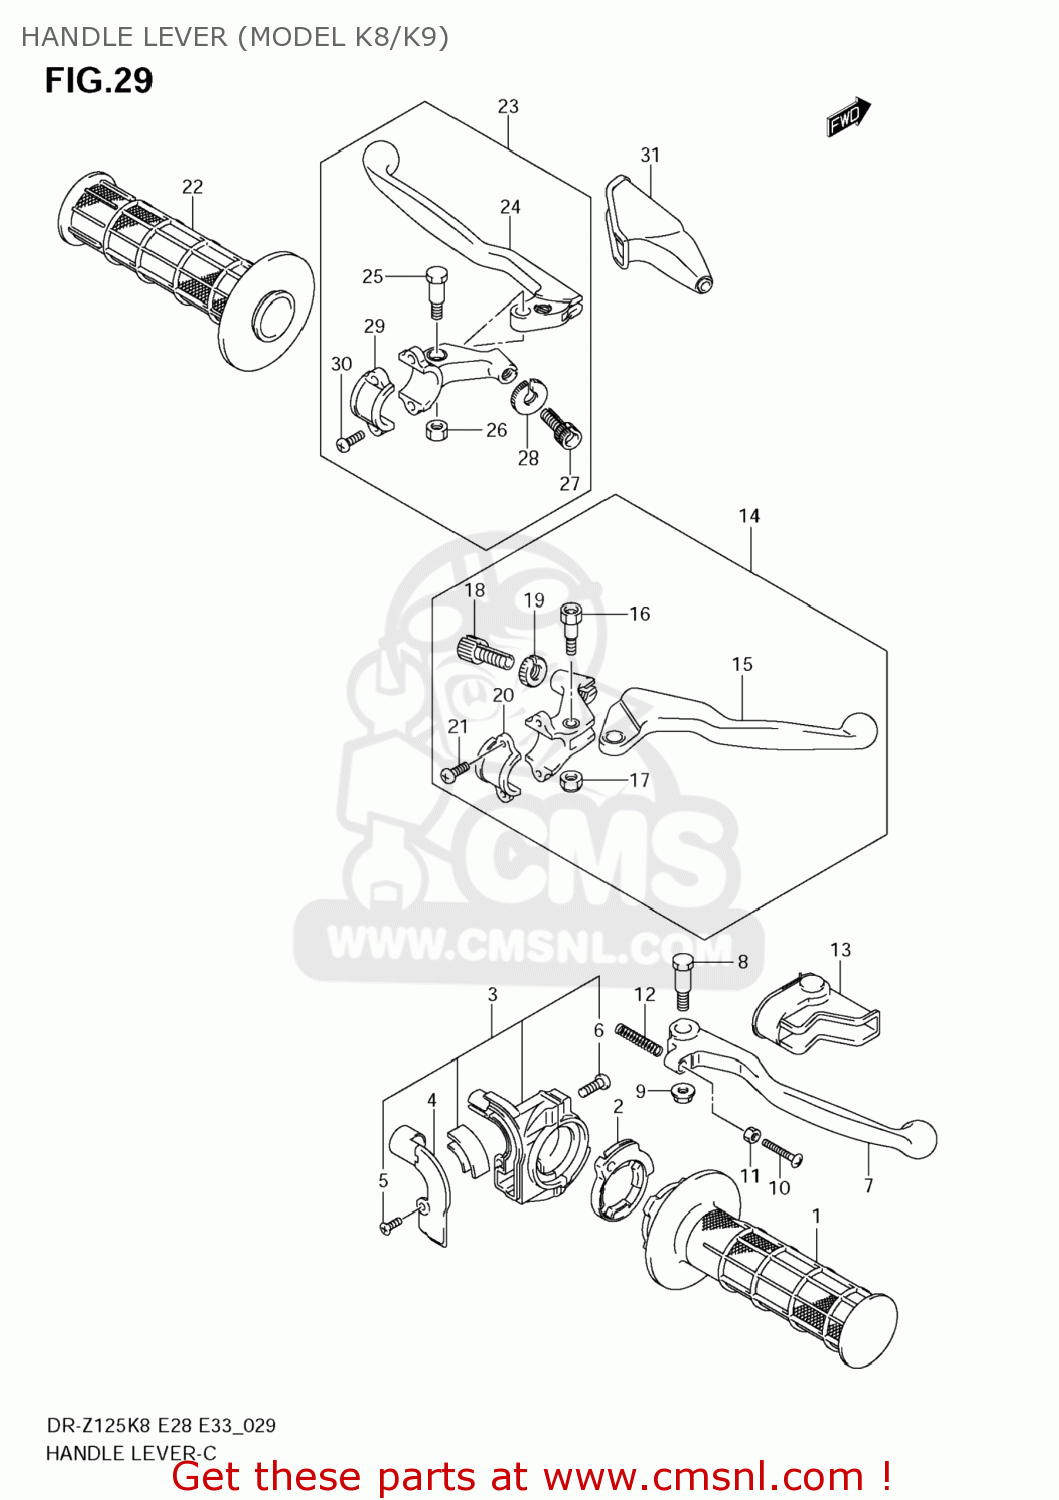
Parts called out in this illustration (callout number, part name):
1	GRIP,THROTTLE
2	ROTOR,THROTTLE GRIP
3	CASE ASSY,THROTTLE
4	COVER,THROTTLE CASE
5	SCREW
6	SCREW
7	LEVER,BRAKE
8	BOLT,BRAKE LEVER
9	NUT
10	BOLT,ADJUST
11	NUT
12	SPRING,RETURN
13	COVER,BRAKE LEVER
14	LEVER ASSY,BRAKE
15	LEVER,BRAKE
16	BOLT,LEVER
17	NUT
18	ADJUSTER,CABLE
19	NUT,CABLE ADJUSTER
20	BRACKET,CLUTCH LEVER HOLDER
21	SCREW
22	GRIP,L
23	LEVER ASSY,CLUTCH
24	LEVER,CLUTCH
25	BOLT,LEVER
26	NUT
27	ADJUSTER,CABLE
28	NUT,CABLE ADJUSTER
29	BRACKET,CLUTCH LEVER HOLDER
30	SCREW(5X14)
31	COVER,CLUTCH LEVER
